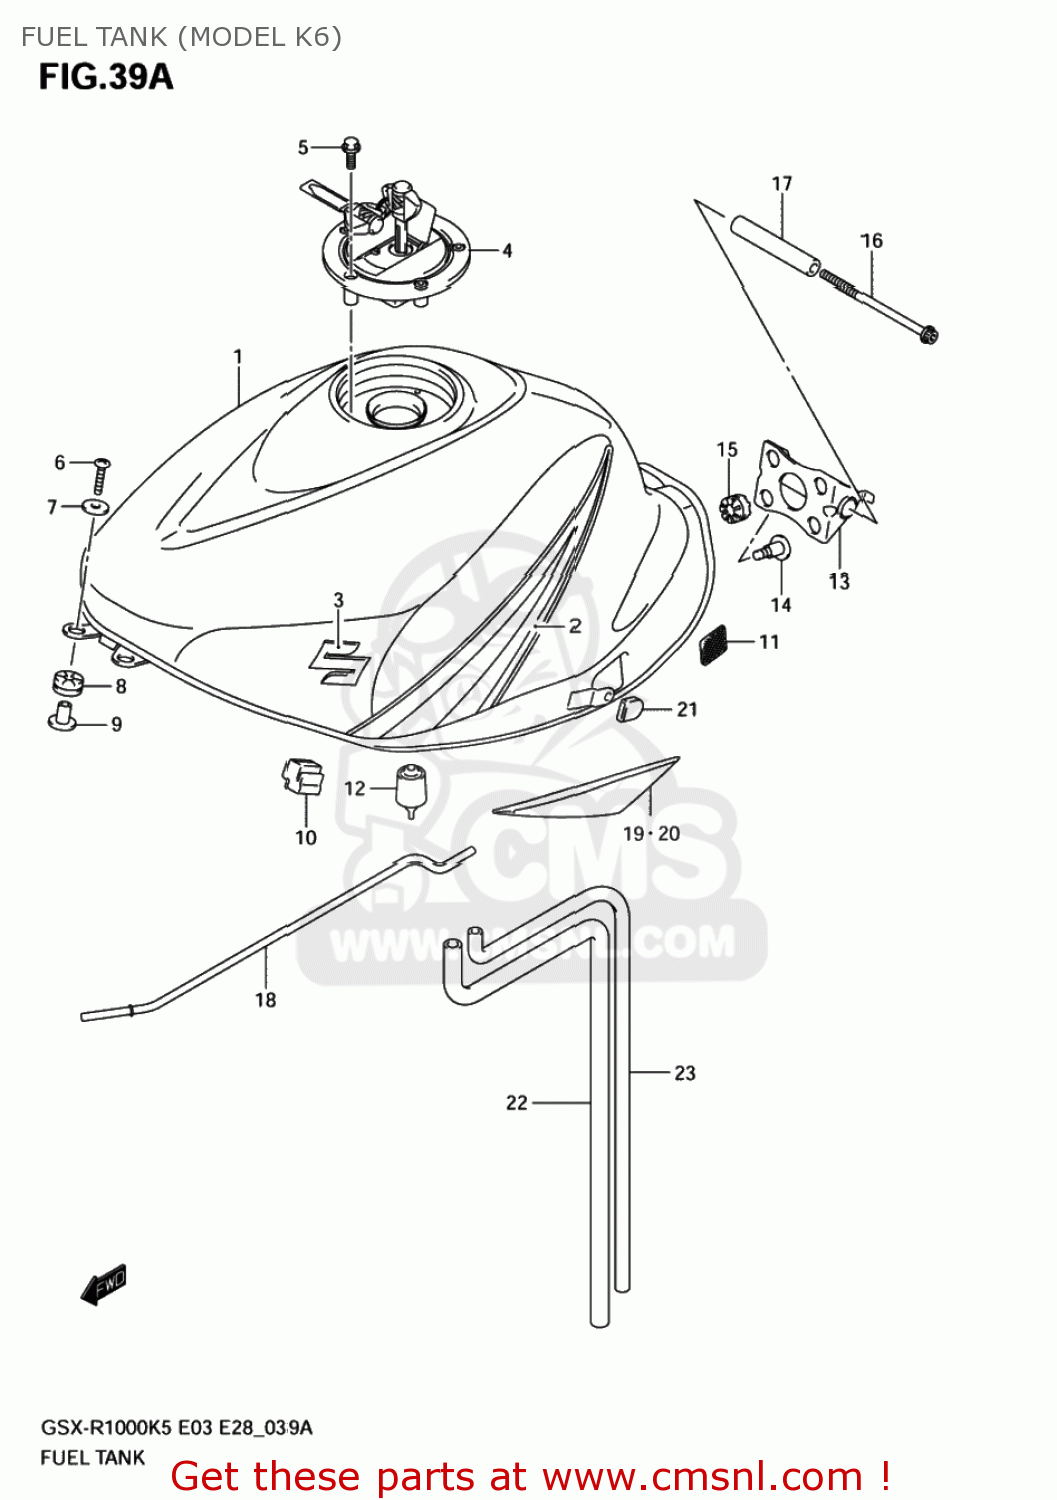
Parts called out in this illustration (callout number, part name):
1	TANK ASSY,FUEL(RED)
2	TAPE SET,FUEL TANK
3	EMBLEM,S
4	CAP SET,FUEL TANK
5	BOLT(5X20)
6	SCREW(6X25)
7	WASHER(6.5X22X1.6)
8	CUSHION,FUEL TANK FR
9	SPACER,FUEL TANK FR
10	CUSHION,FUEL TANK SIDE
11	FASTENER
12	CUSHION,FUEL TANK RR
13	BRACKET,FUEL TANK NO.1
14	SCREW,FUEL TAN
15	CUSHION
16	BOLT(6X110)
17	SPACER,FUEL TANK RR
18	STAY,FUEL TANK
19	COVER,FUEL TANK,R
20	COVER,FUEL TANK,L
21	CUSHION
22	HOSE,TANK WATER DRAIN
23	HOSE,TANK BREATHER
